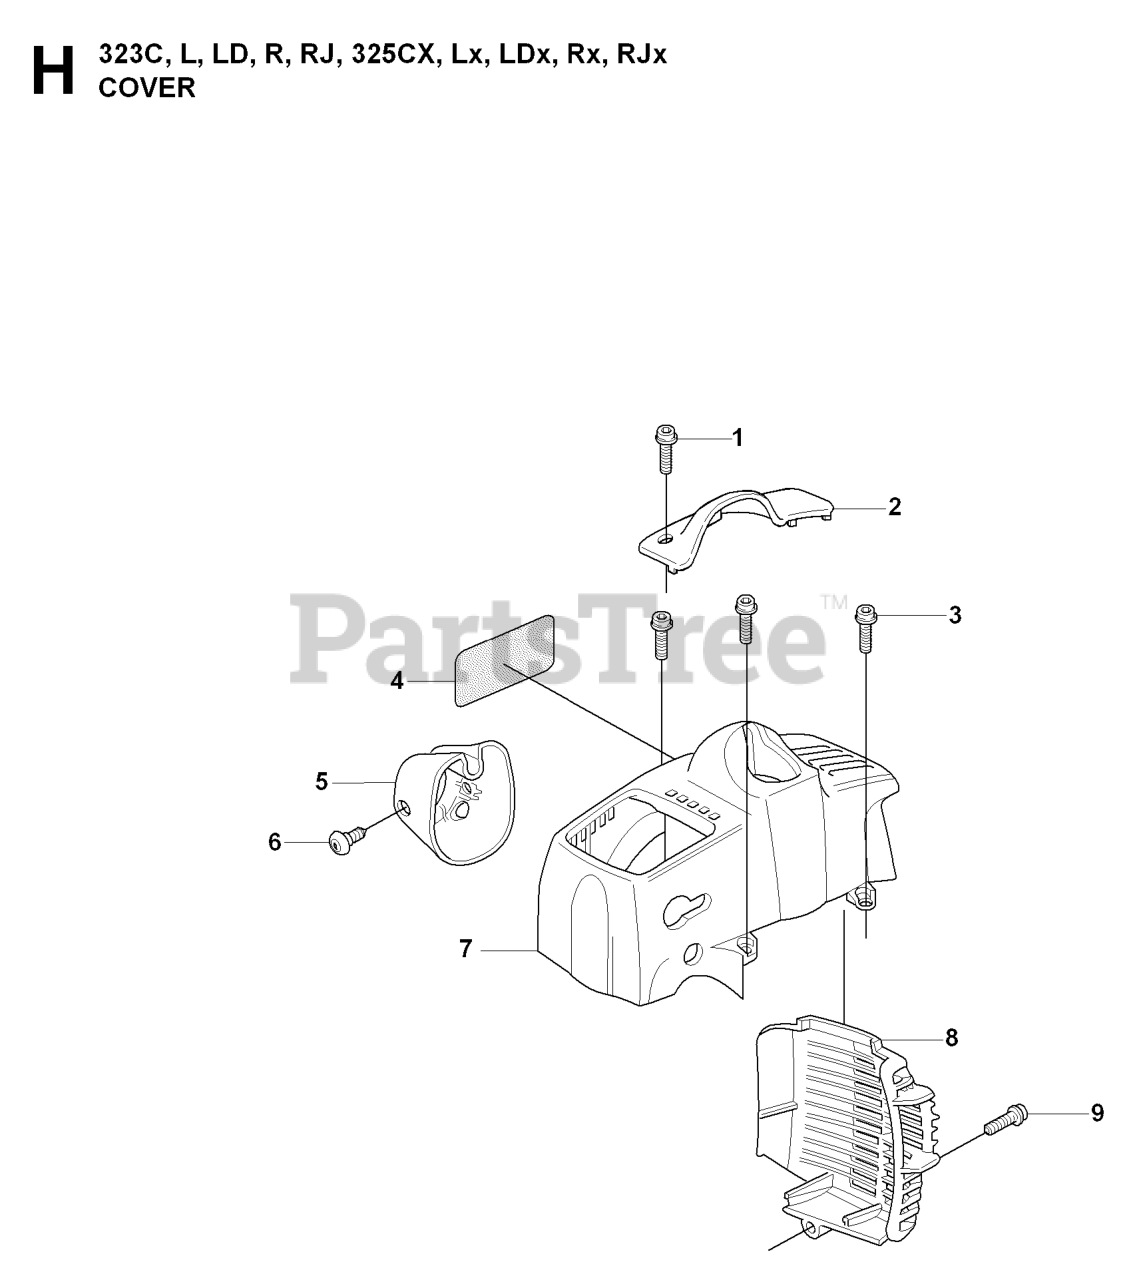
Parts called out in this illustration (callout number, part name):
3	SCREW
4	DECAL CYLINDER COVER
4	DECAL, 323L CYLINDER COVER
6	SCREW MT5X11
7	RP CYLINDER COVER
8	MUFFLER COVER
9	SCREW
